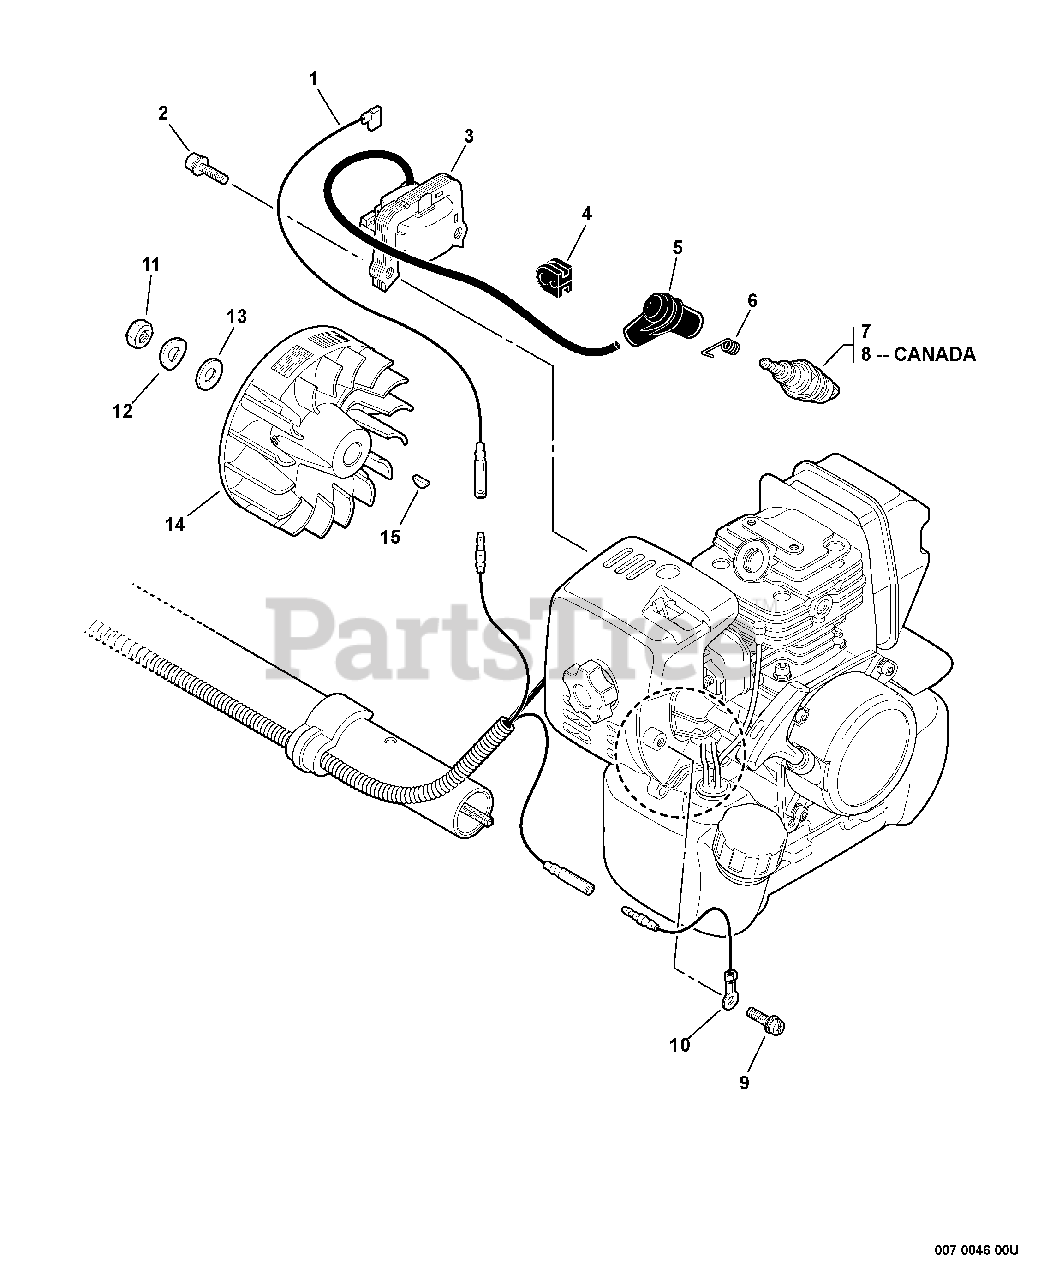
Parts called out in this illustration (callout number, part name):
1	LEAD 170 MM
2	BOLT 5×20
3	COIL, IGNITION
5	CAP, SPARK PLUG
6	TERMINAL, SPARK PLUG
7	SPARK PLUG - BPM8Y
8	SPARK PLUG - BPMR8Y
9	SCREW 5×10
10	LEAD - GROUND
11	NUT 8×1.25
12	WASHER, SPRING 8
13	WASHER 8.5×16×1.2
14	FLYWHEEL
15	KEY, WOODRUFF
